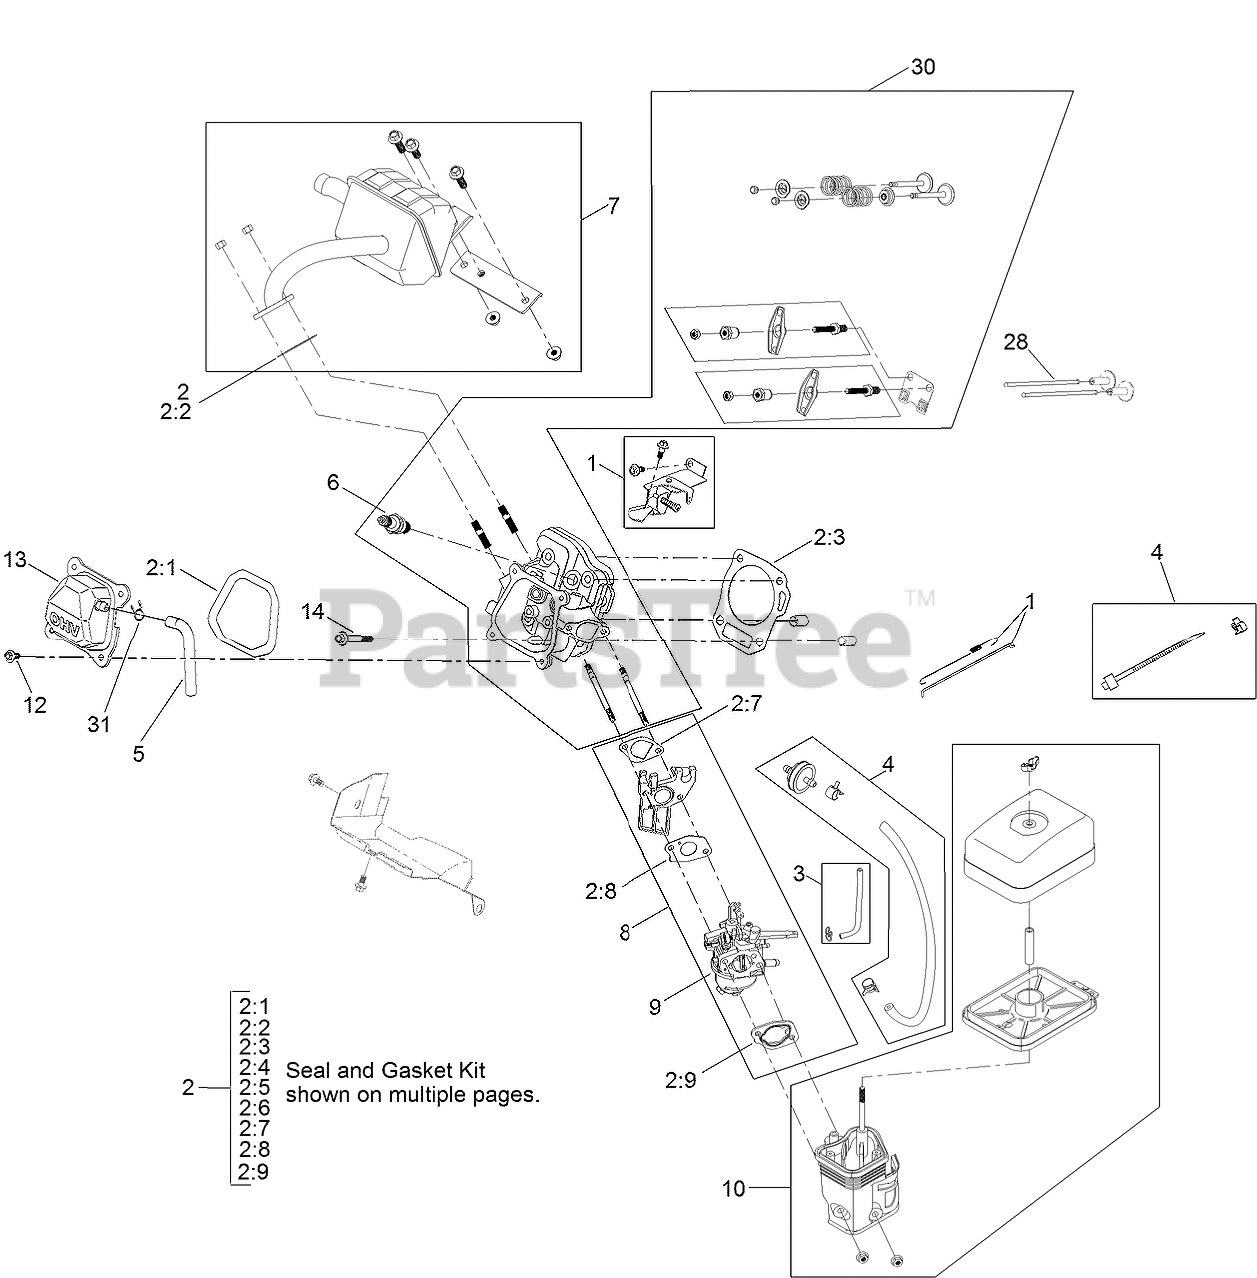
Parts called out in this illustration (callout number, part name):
1	GOVERNOR KIT
2	GASKET AND SEAL KIT
2:1	GASKET-COVER, VALVE
2:2	GASKET-EXHAUST
2:3	GASKET-HEAD, CYLINDER
2:5	SEAL-OIL
2:6	GASKET-COVER, CRANKCASE
2:7	GASKET-CARBURETOR
2:8	GASKET-CARBURETOR
2:9	GASKET-CARBURETOR
3	PRIMER LINE KIT
4	FUEL LINE KIT
5	TUBE-BREATHER
7	MUFFLER KIT
8	CARBURETOR KIT
9	CARB REPAIR KIT WITH GASKETS
10	HEATER BOX KIT
12	SCREW-HHF
13	VALVE COVER ASM
14	SCREW-HHF
28	ROD-PUSH
30	COMPLETE HEAD ASM
31	CLAMP-HOSE
